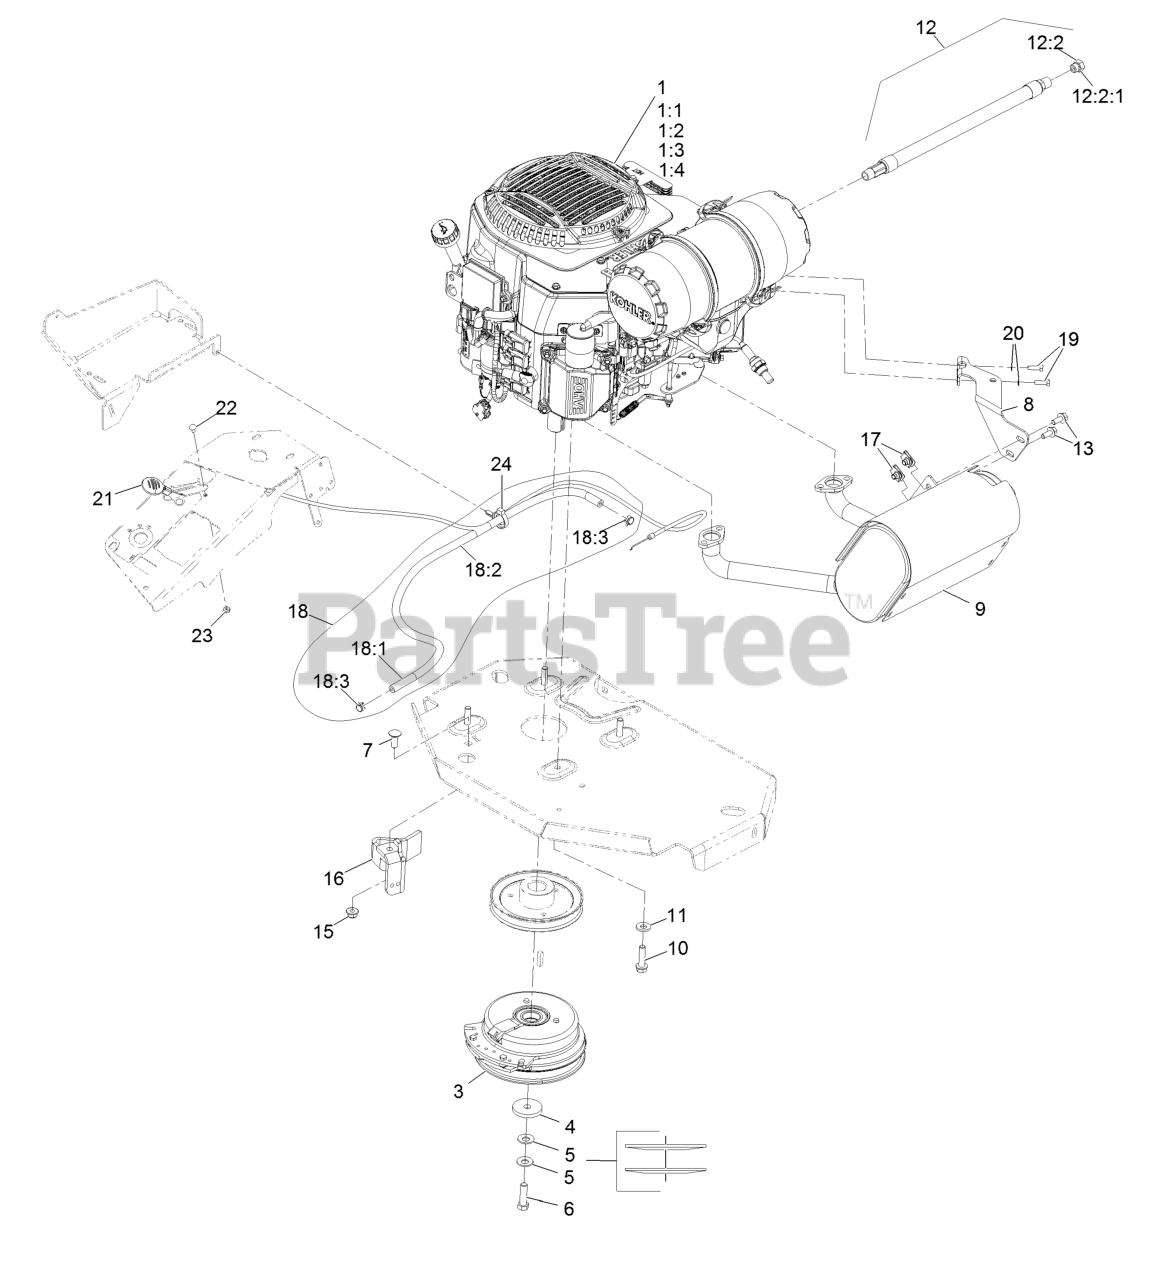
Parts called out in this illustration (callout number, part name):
1:1	Kohler 52 050 02-S Engine Oil Filter
1:2	Kohler 25 083 01-S Engine Air Filter
1:3	Kohler 25 083 04-S Safety Filter
1:4	Kohler 25 050 42-S Fuel Filter
3	Clutch Kit
4	Washer-Clutch
5	Washer-Spring Disc 7/16
6	Screw-HH 7/16-20 X 1 1/2 W/Loctite
7	Bolt-Carriage 3/8-16 X 1
8	Muffler Bracket Kit
9	Muffler Kit
10	Screw-HWH 3/8-16 X 1 1/2 Taptite
11	Washer-Spring Disc 3/8
12	Oil Drain Hose ASM
12:2	Plug-W/O-Ring
12:2:1	O-Ring
13	Screw-HH Flg 5/16-18 X 3/
15	Nut-Nyloc 3/8-16 Flg
16	Clutch-Anchor
18	Fuel Line ASM
18:1	Hose-Fuel Line 38 1/4"
18:2	Sleeve-Thermal
18:3	Clamp-Hose
19	Screw-HH M6-1 X 20Mm W/Patch
20	Washer-Spring Disc 1/4
21	ASM,Throttle Cable
22	Bolt-Carriage #10-24 X 1/2
23	Nut-Nyloc #10-24
24	Clamp-Hose
